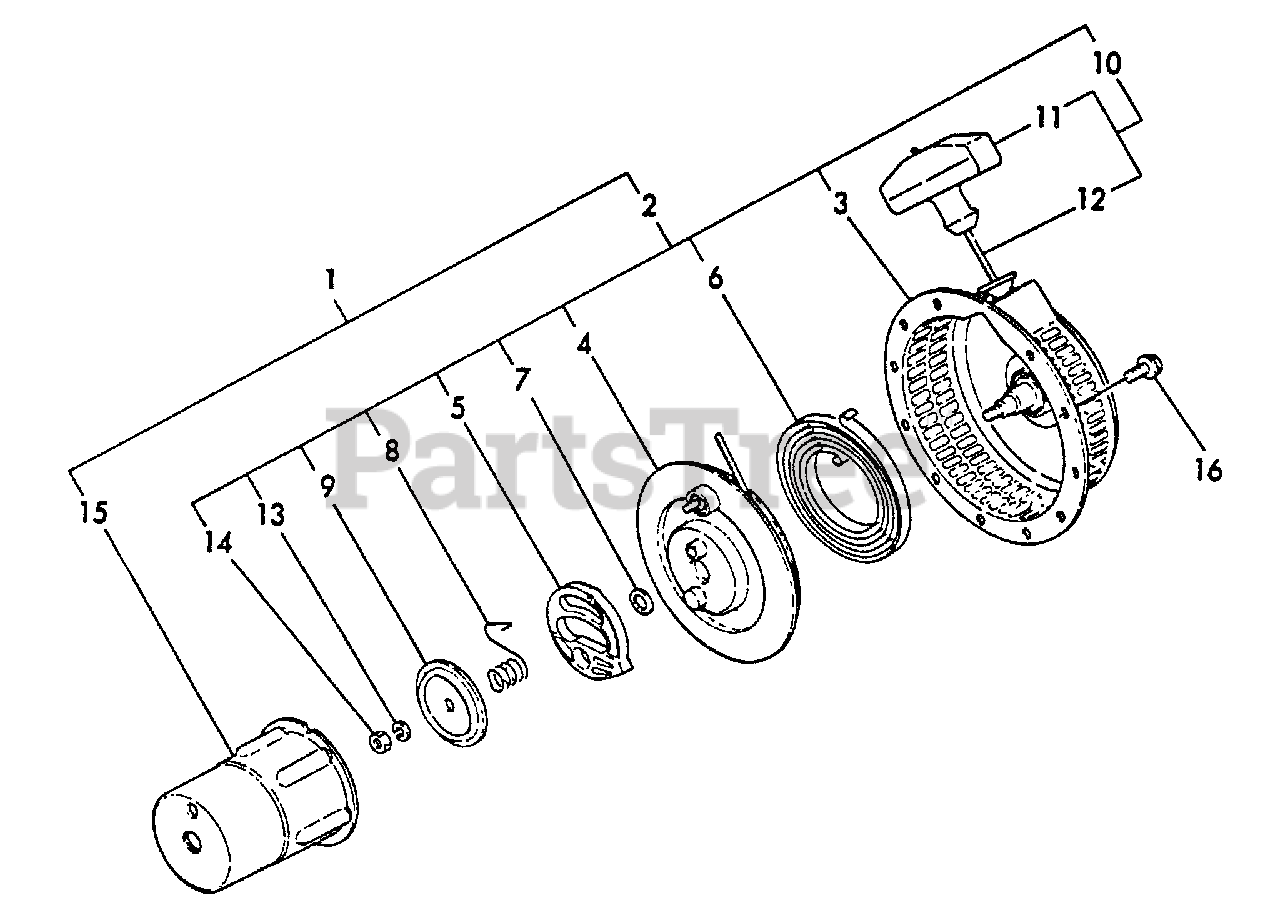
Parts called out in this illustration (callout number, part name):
1	STARTER ASSY
2	STARTER ASSY
3	CASE, STARTER
4	PULLEY
7	WASHER, THRUST
8	SPRING, FRICTION
9	PLATE, FRICTION
10	STARTER ROPE ASSY
11	GRIP, STARTER
12	ROPE, STARTER
13	LOCKWASHER - 6
14	NUT - 6
15	PULLEY, STARTER
16	BOLT - 6X8 -- PLATED
